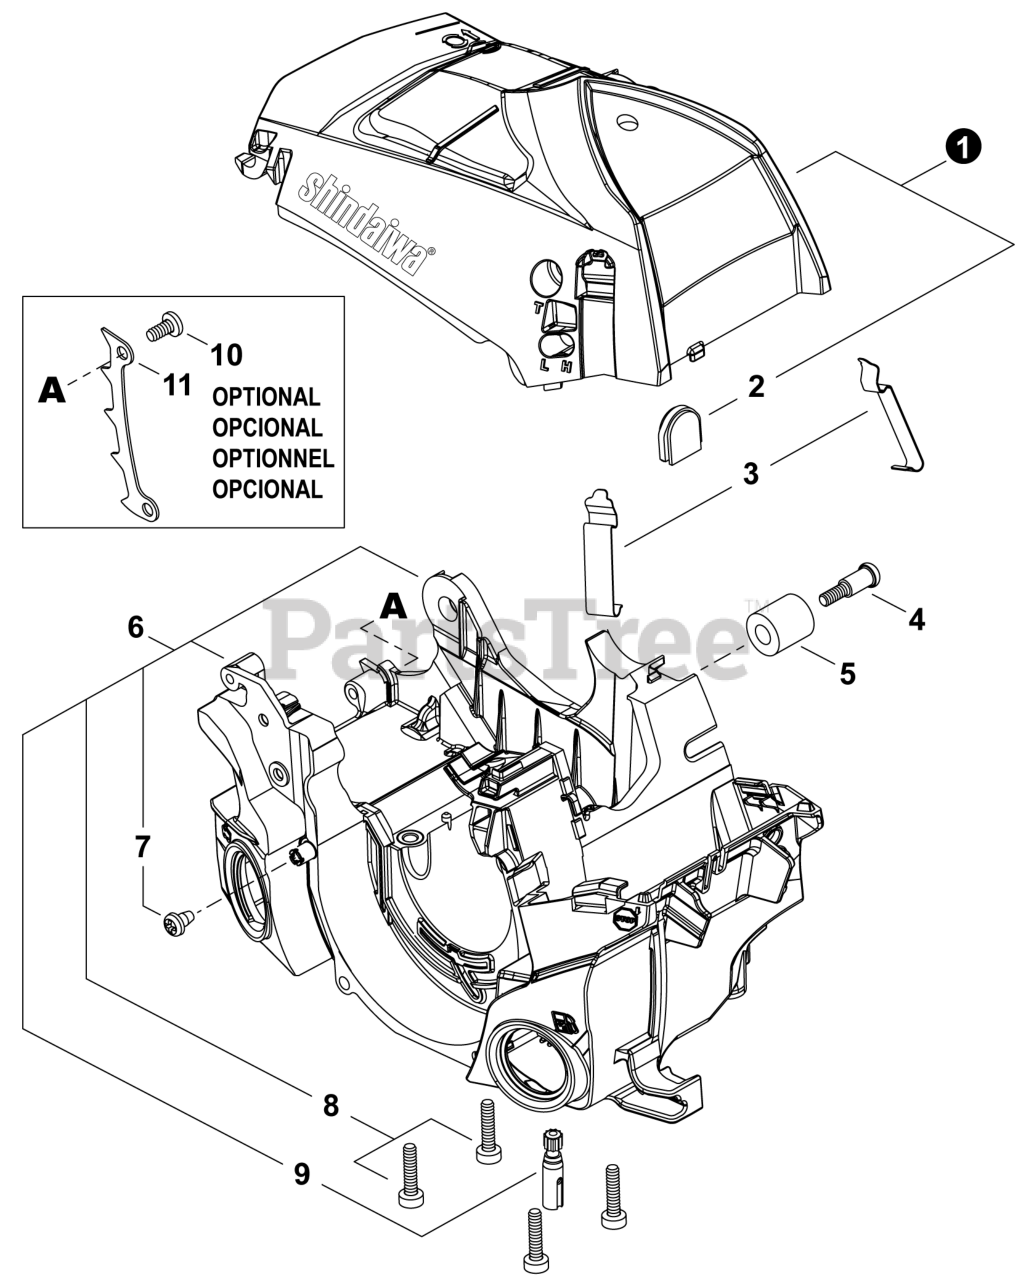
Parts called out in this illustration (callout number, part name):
1	COVER ASSY, ENGINE
4	BOLT 5x12
5	CATCHER, CHAIN
6	HOUSING ASSY, ENGINE
7	SCREW, TAPPING 4x6
8	BOLT, TORX 5x20
9	AUTO-OILER ASSY
10	BOLT, TORX 5x16
11	SPIKE, BUMPER
